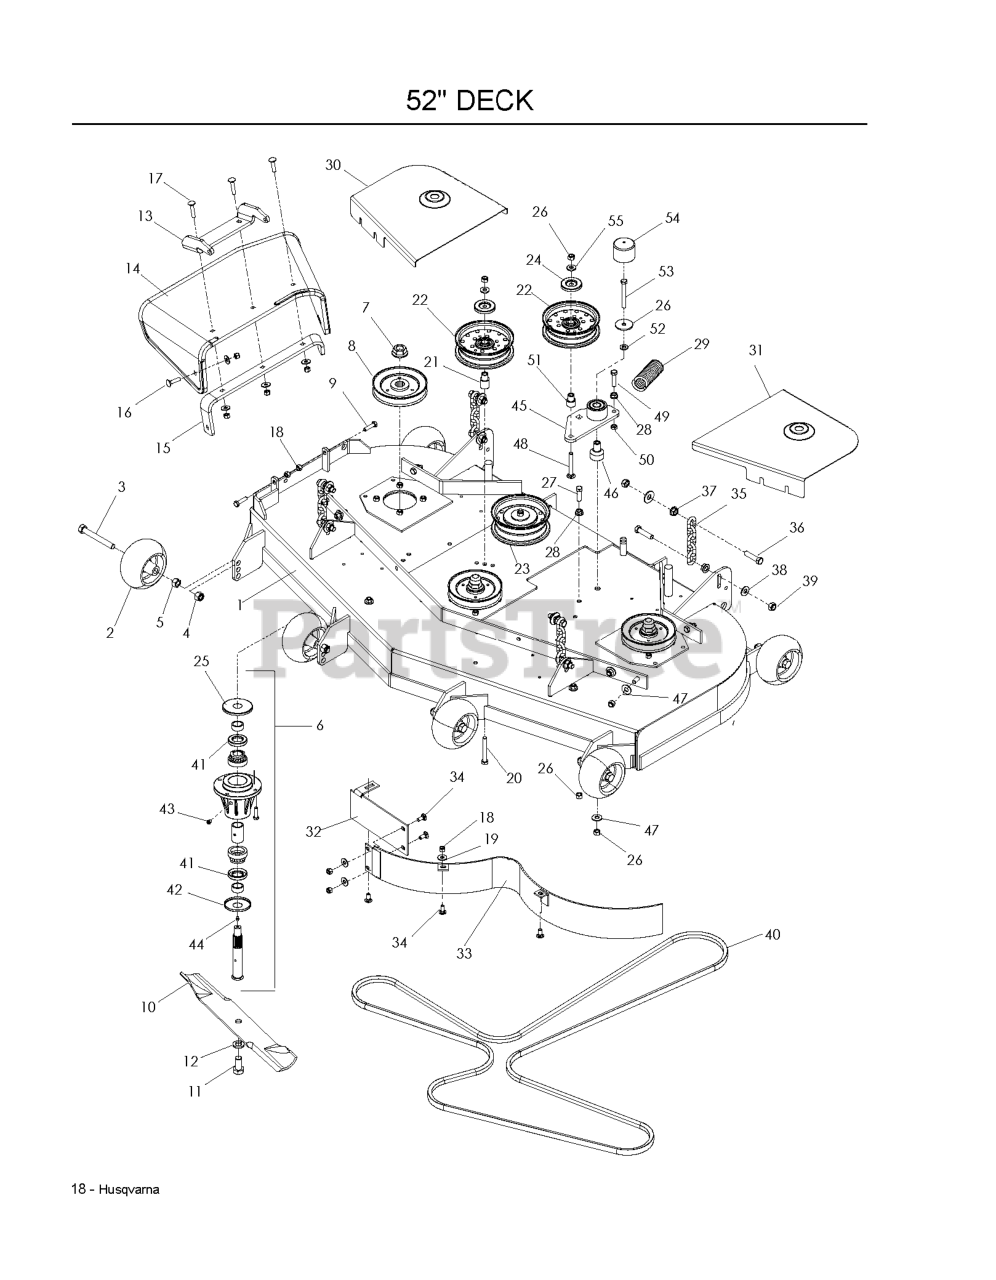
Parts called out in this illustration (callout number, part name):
1	DECK W/DECALS 52" HUS
2	GAUGE WHEEL
3	HCS 1/2-13 X 4 GR 5 ZD
4	NUT 1/2-13 HEX NYLOC ZD
5	NUT HEX 1/2
6	HOUSING ASM, 52/61
7	NUT FLANGE 3/4-16
8	PULLEY, 52
9	HCS 5/16C X 1 1/4
10	BLADE OEM 18"
11	HCS 5/8F X 1 1/4
12	LOCKWASHER 5/8
13	PIVOT BRACKET - CHUTE
14	CHUTE, RUBBER DISCHARGE 52/61"
15	BRKT, REINF - CHUTE 52/61"
16	BOLT, CARRIAGE 5/16X1-1/4
17	RHSNB 5/16-18 X 1-1/2 GR 5 ZD
18	NUT 5/16 NYLOC
19	WASHER 5/16 FLAT
20	SCREW 3/8C X 2 3/4 HEX CAP
21	IDLER BUSHING
22	IDLER PULLEY
23	IDLER PULLEY (TALL)
24	DUST SHIELD
25	TOP DUST CAP
26	NUT 3/8-16 NYLOC
27	HCS 3/8C X 1 1/4 GR5
28	NUT 3/8C WHIZ
29	DECK SPRING
30	RT 52 SHIELD, ORANGE
31	LT 52 SHIELD ORANGE
32	MAIN BAFFLE 52"
33	CENTER BAFFLE - 52"
34	BOLT 5/16C X 3/4" CARRIAGE
35	LIFT CHAIN
36	HCS 7/16 - 14 X 1 3/4
37	NUT 7/16C WHIZ
38	WASHER 7/16 FLAT ZD
39	7/16-14 HEX NUT W/NYL RING ZD
40	BELT, DECK
41	SHAFT SEAL
42	BOTTOM DUST CAP
43	PLUG-VENTED
45	ARM-IDLER W/BRG
46	PIVOT, BEARING
47	WASHER 3/8 FLAT
48	RHSNB 3/8-16 X 2.75
49	HCS 3/8-16 X 1-1/2
50	NUT 3/8-16 HEX JAM
51	BUSHING, IDLER
52	WASHER 3/8 SAE FLAT
53	HCS 3/8C X 3
54	CAP, VINYL
55	WASHER, 3/8 THICK
